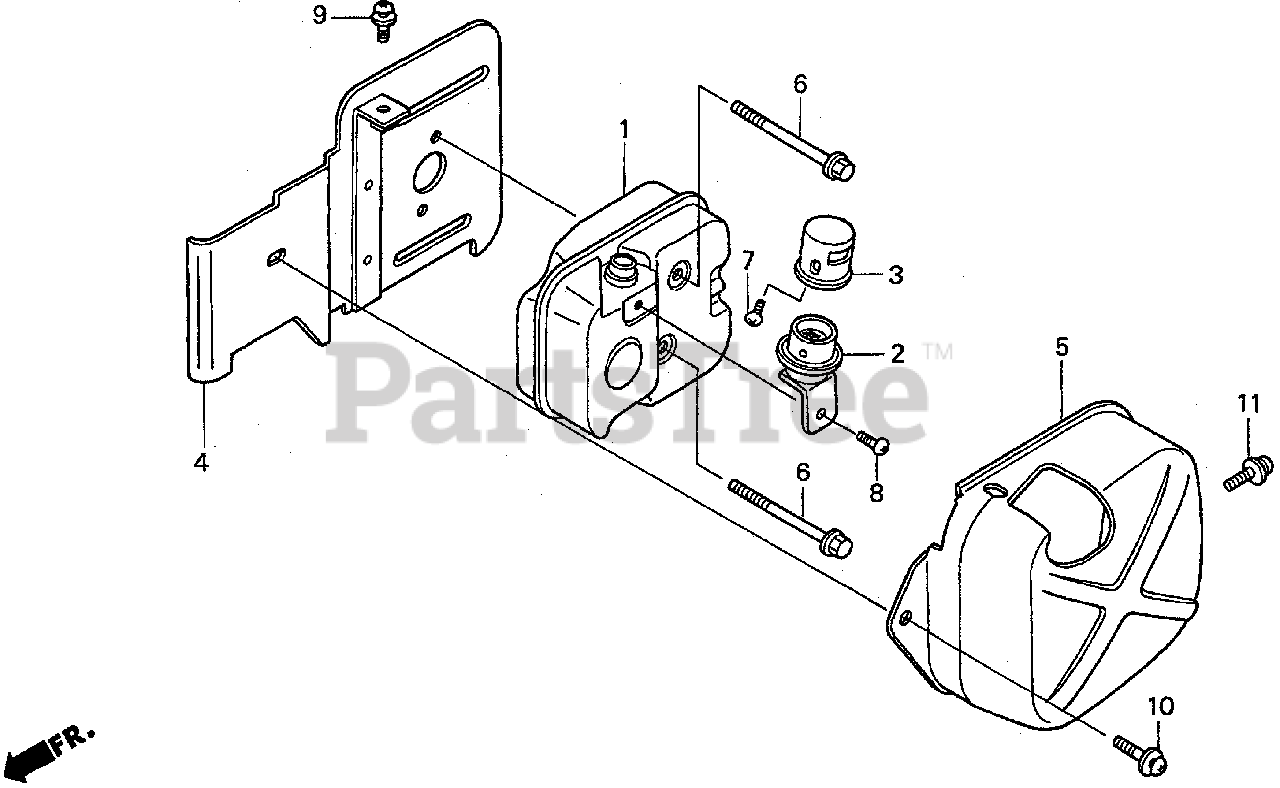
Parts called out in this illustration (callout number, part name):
1	MUFFLER COMP.
2	ARRESTER, SPARK
3	DEFLECTOR
4	GUIDE, AIR EX.
5	INNER COVER, TOP
6	BOLT, FLANGE (5X50)
7	SCREW, TAPPING (4X6)
8	SCREW-WASHER (4X6)
9	SCREW-WASHER (5X8)
10	SCREW-WASHER (5X10)
11	SCREW-WASHER (5X16)
